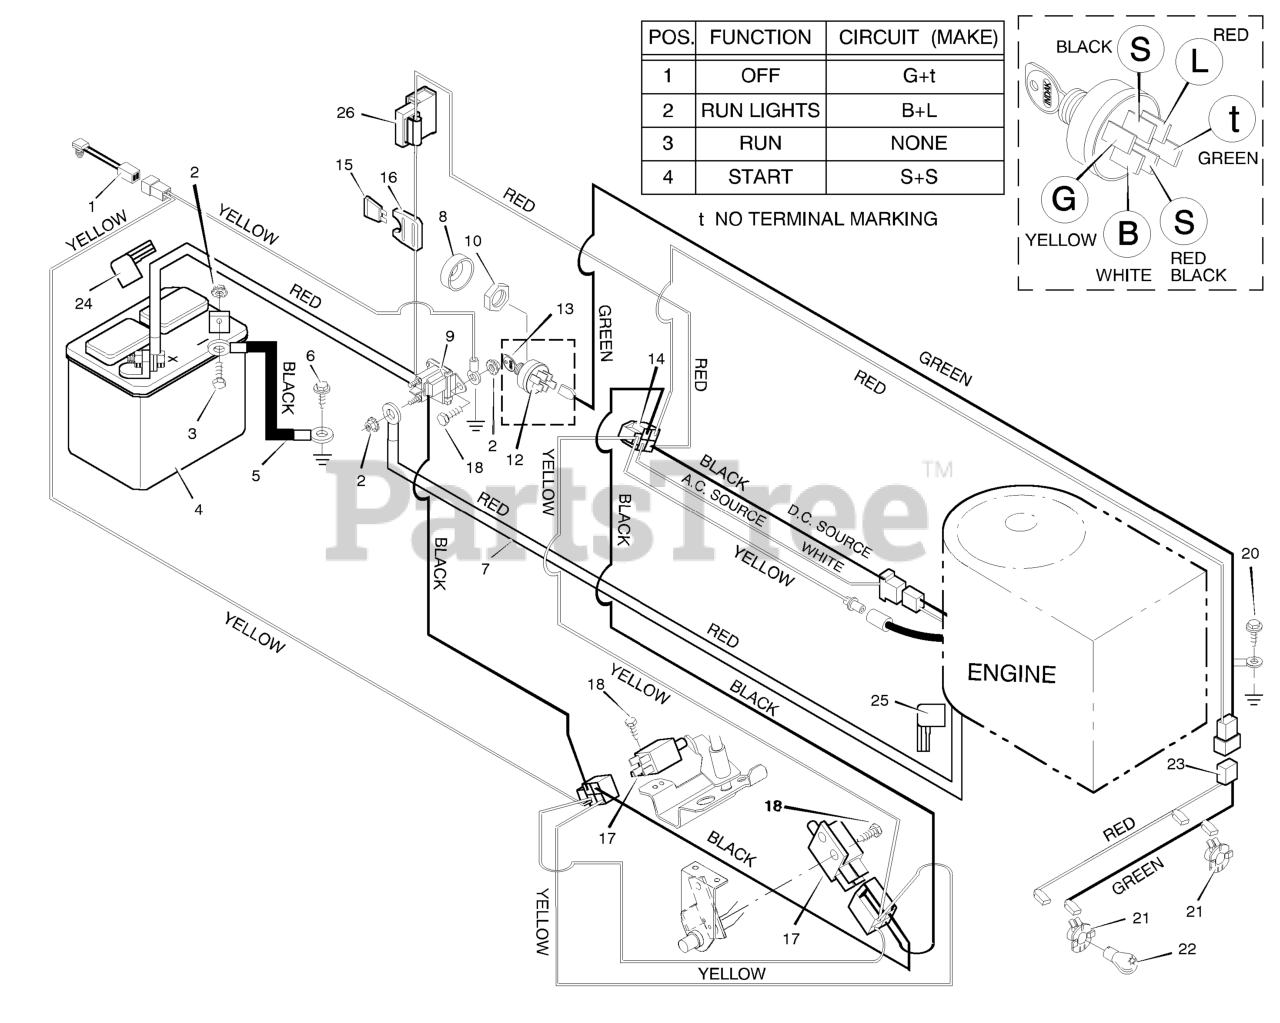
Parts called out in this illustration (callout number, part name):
1	Switch, Seat Sensor
2	Locknut
3	Bolt, Hex
4	Battery
5	Cable, Battery Ground
7	Cable, Red Battery
8	Cap, Ignition
9	Solenoid
10	Nut
12	Switch, Ignition
13	Key, Ignition
14	Harness, Chassis Wire
16	Holder, Fuse
17	Switch, Clutch
20	Screw
21	Socket, Light
22	Bulb, Light
23	Harness, Light Wire
24	Cover, Terminal
25	Cover,
26	Ammeter
